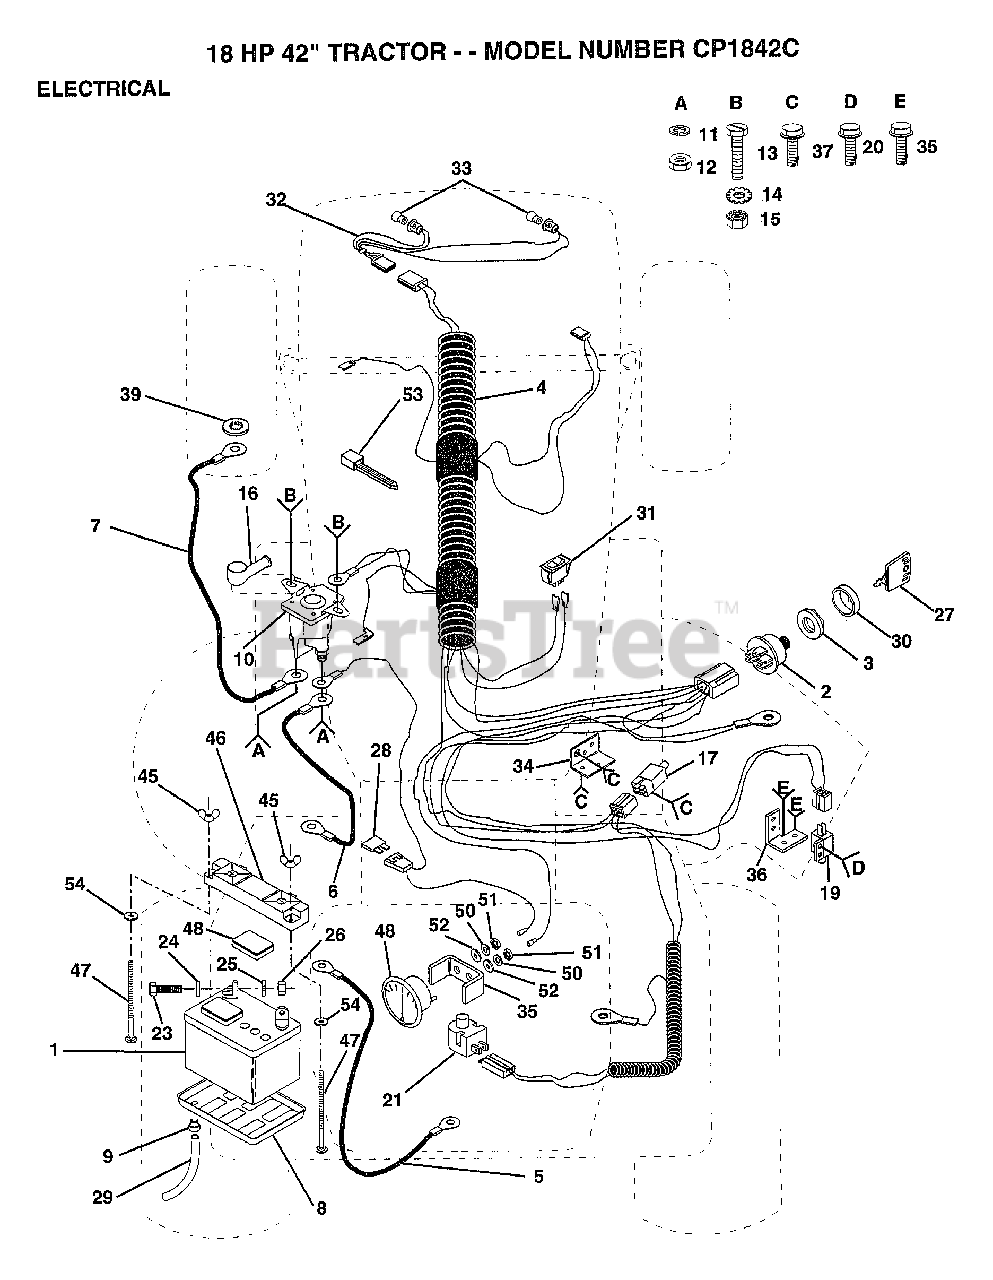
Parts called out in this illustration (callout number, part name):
3	NUT IGNITION
4	IGNITION HARNESS
5	CABLE T
6	CABLE-BATTERY T
7	"CABLE T, BATTERY"
8	"TRAY T, BATTERY"
9	HOSE CLAMP T
12	NUT
13	BOLT
15	NUT
17	SWITCH INTERLOCKT
19	SWITCH-INTER. GT
20	SCREW
21	SWITCH SEAT
22	"CAP,BATTERY "
23	BOLT LT
24	WASHER
25	LOCKWASHER
27	KEY
28	FUSE HYT
29	"DRAIN TU T, BATT"
31	SWITCH LT
32	"HARNESS,LIGHT SOC"
34	BRACKET LT
35	SCREW
36	SWITCH BRACKET
37	SCREW
39	LOCKWASHER
47	BOLT
48	AMMETER T
52	WASHER
53	WIRE TIE
54	WASHER.3/4X1X18GA
